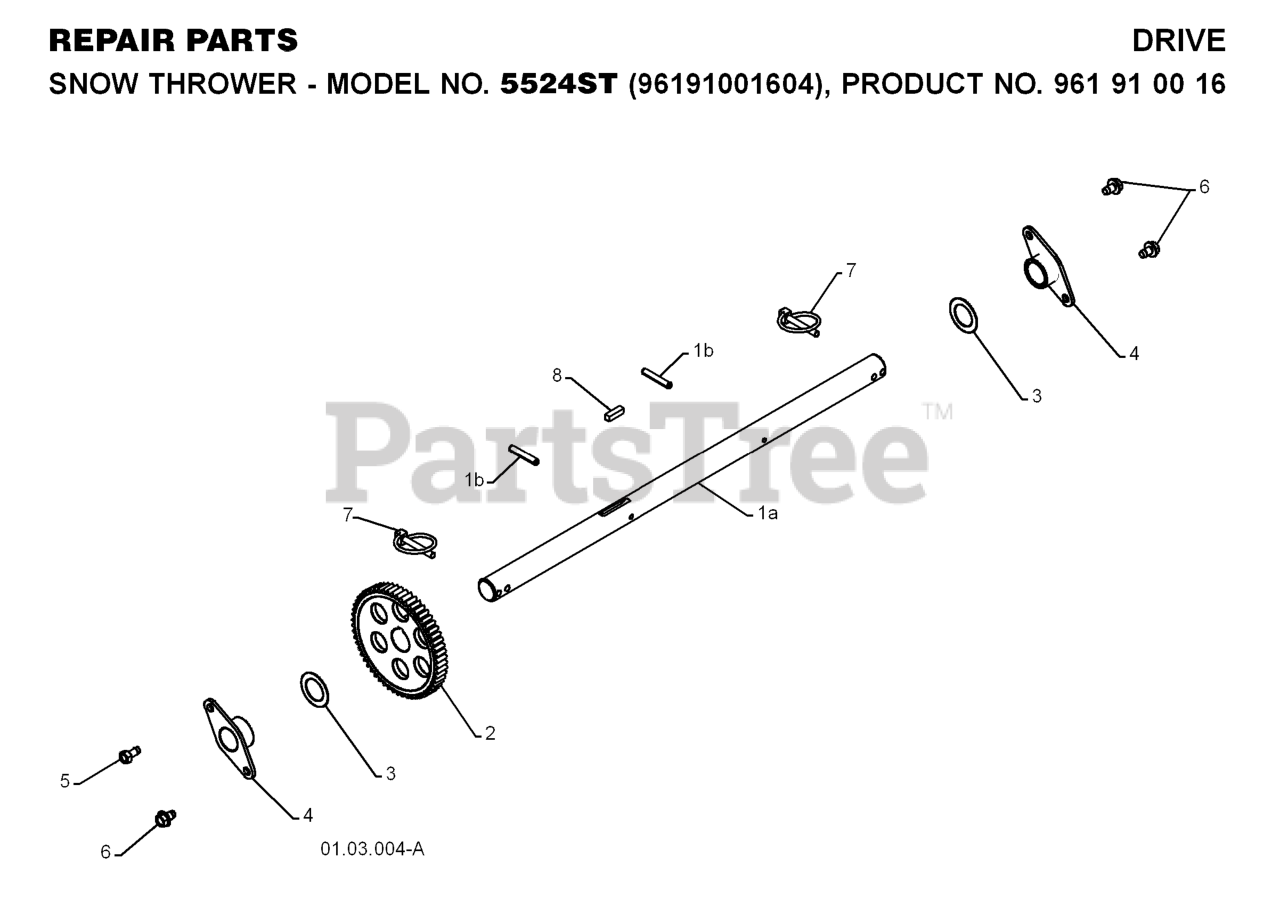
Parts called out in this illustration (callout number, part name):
1	AXLE.SHAFT.ASM.W/ROLPIN.NON-PS
1A	SHAFT.AXLE.16".SNOW
1B	PIN.ROLL.3/16
2	GEAR, AXLE (58T)
3	WASHER TRUST 1"
4	BEARING, AXLE
6	Screw 5/16-18 x 1/2 Hex, Self Tapping 5/16-18 x 1/2
7	PIN KLIK, 1/4
8	KEY, SQUARE 1/4 X .875
